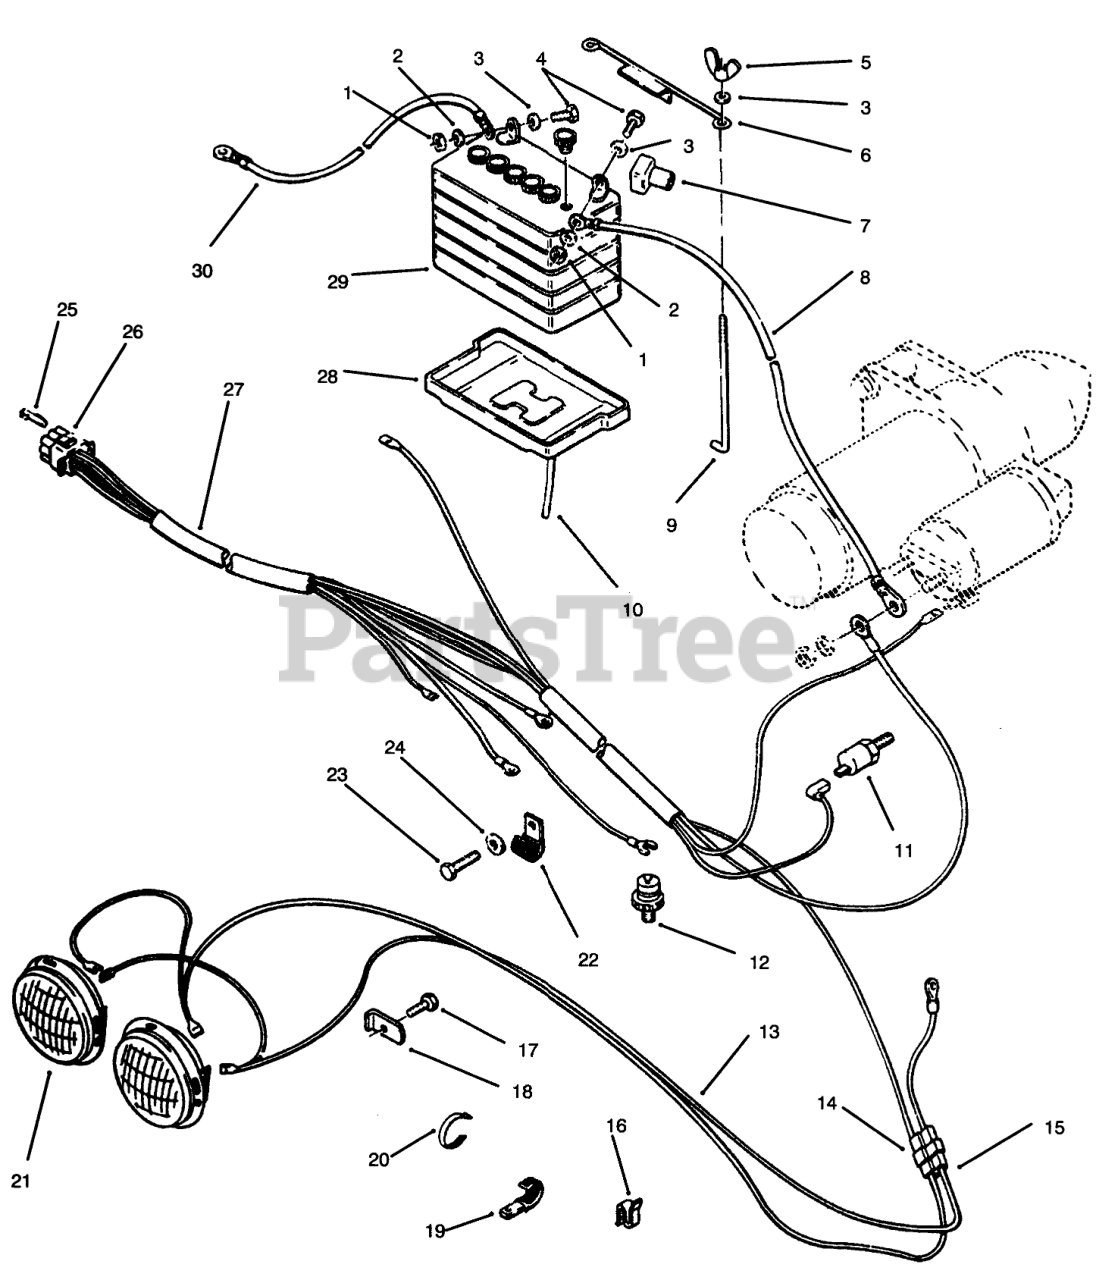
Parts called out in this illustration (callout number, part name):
1	NUT-LOCK, NI
2	WASHER-LOCK
3	WASHER-FLAT
4	SCREW-HH
5	NUT-WING
6	HOLDDOWN-BATTERY
7	Boot
8	ASS'Y-WIRE
9	HOOK-BATTERY RETAIN
10	TUBE-21" BATTERY DRAIN
11	HIGH TEMPERATURE
12	SWITCH - OIL PRESSURE
13	HARNESS-HEADLIGHT
14	MALE CONNECTOR
15	CONNECTOR BODY
16	SPEED CLIP
17	SCREW-HWH
18	LOCK-HEADLIGHT
19	CLIP
20	PLASTIC TIE
21	HEADLAMP
22	CLIP-WIRE
23	SCREW-HWH
24	LOCKWASHER 1/4 IT
25	CONTACT SOCKET
26	CONNECTOR CAP
27	HARNESS - ENGINE WIRE
28	TRAY-BATTERY
29	Battery
30	ASS'Y-WIRE
